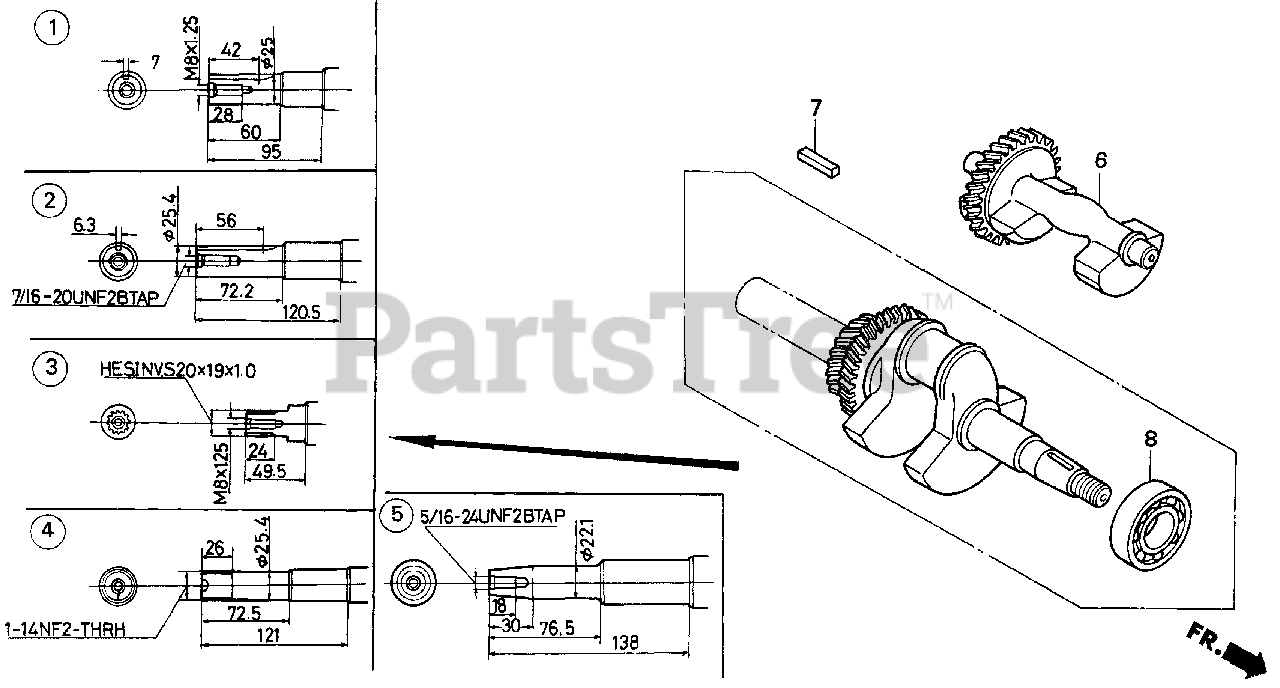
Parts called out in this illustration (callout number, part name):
2	CRANKSHAFT (Q-TYPE)(BALANCER)
6	WEIGHT, BALANCER
8	BEARING, RADIAL BALL (6206 SH)
